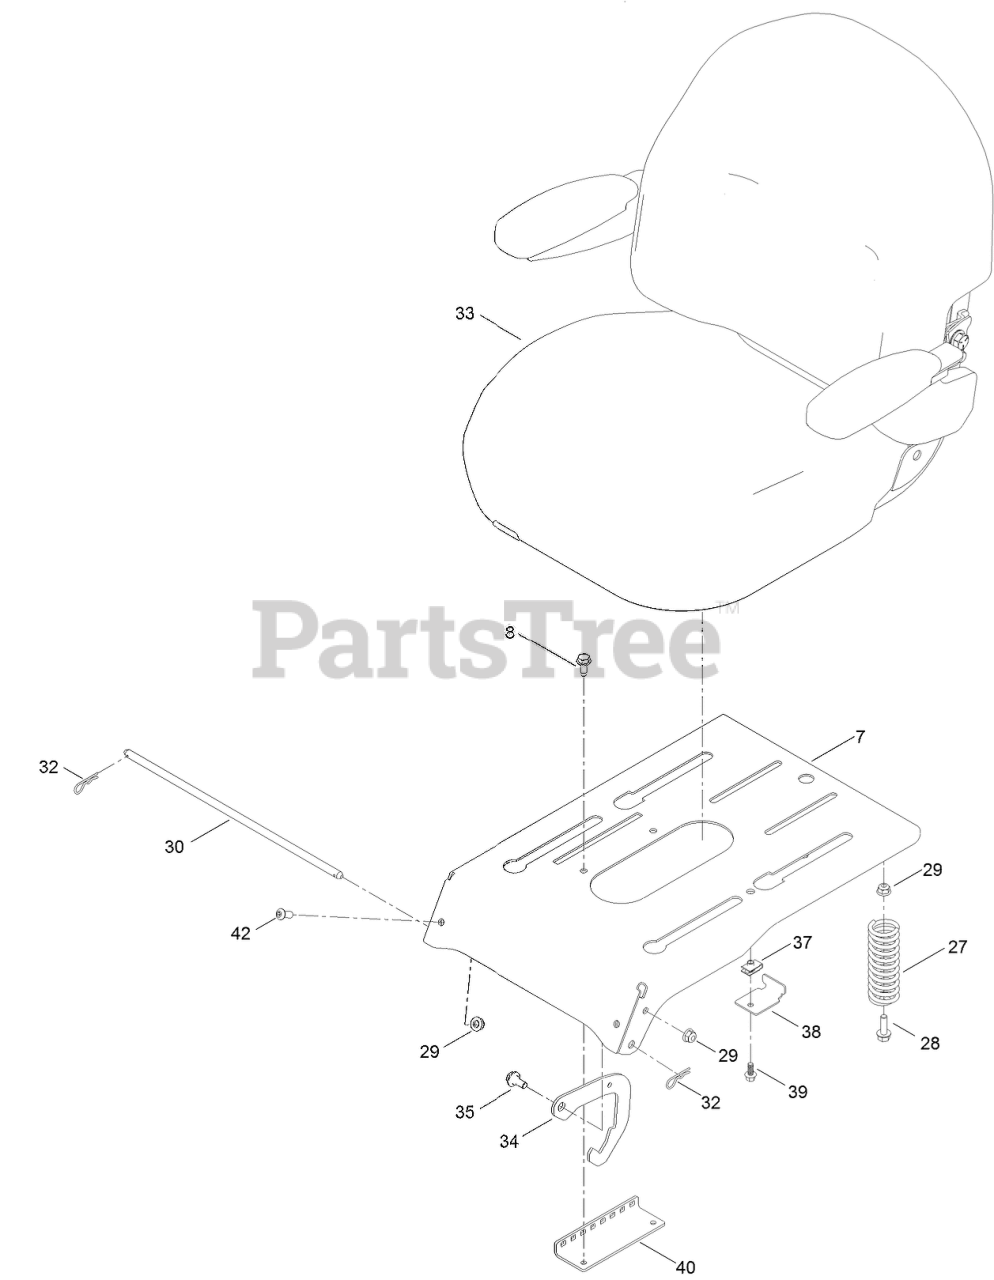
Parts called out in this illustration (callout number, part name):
7	PAN-SEAT, DELUXE
8	SCREW-HWHTF
27	SPRING-COMPRESSION
28	SCREW-HHF
29	NUT-HF, NI
30	ROD-PIVOT, NARROW
32	PIN-COTTER
33	SEAT ASM
34	SEAT LATCH
35	SCREW-SHOULDER
38	BRACKET-STOP, SEAT
39	SCREW-HHF
40	BRACKET-LATCH, SEAT
42	SCREW-HSBH
